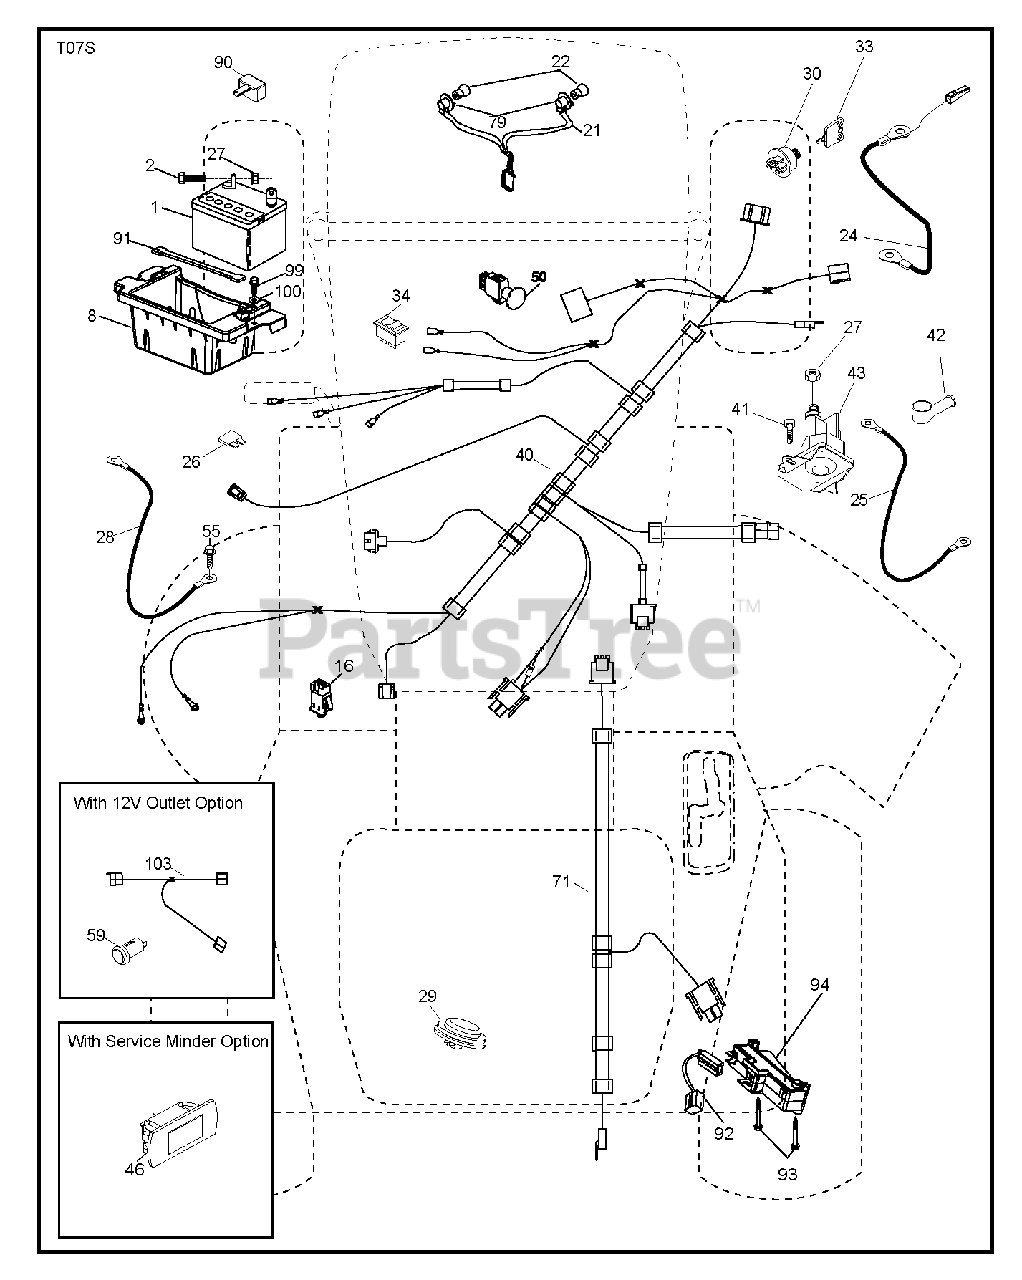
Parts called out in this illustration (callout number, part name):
1	REPL BY 532 12 38-99
2	BOLT.HEX.1/4.X.3/4.DICHROMATE
8	BOX.BATTERY.MOUNT.FRONT.LT
16	SWITCH INTERLOOK PUSH-IN
21	HARNESS ASSY LIGHT
22	LIGHTBULB
24	Battery Cable with Wire, Front 8 Ga 8
25	CABLE.STARTER.6G.BL/RED.17.5
26	FUSE 20AMP
27	NUT
28	Ground Cable, 21" Black 8 Ga 90T
29	SWITCH.SEAT.DELTA.OPC.
30	SWITCH.IGN.DELTA.W.LGH.ROS
33	KEY.CHAIN.BLISTER.PACK.GEN.INT
34	SWITCH LT
40	HARNESS.IGN.DASH.HUQ/P
41	SCREW
42	TERMINAL COVER
43	SOLENOID.W/BRASS.PLUNGER
46	GUAGE.SRVCMNDR.HRMTR.
50	PTO SWITCH
55	SCREW 5/16"
71	HARNESS-CHASSIS SUB
79	BULB HOLDER ASM.
90	COVER.TERMINAL.BATTERY
91	STRAP.BATTERY.MOUNT.FRONT
92	HARNESS.PIGTAIL.CONSLE
93	SCREW.PLASTITE
94	MODULE.REVERSE.ROS
99	SCREW HEXWSHR 1/4-20X3/4
